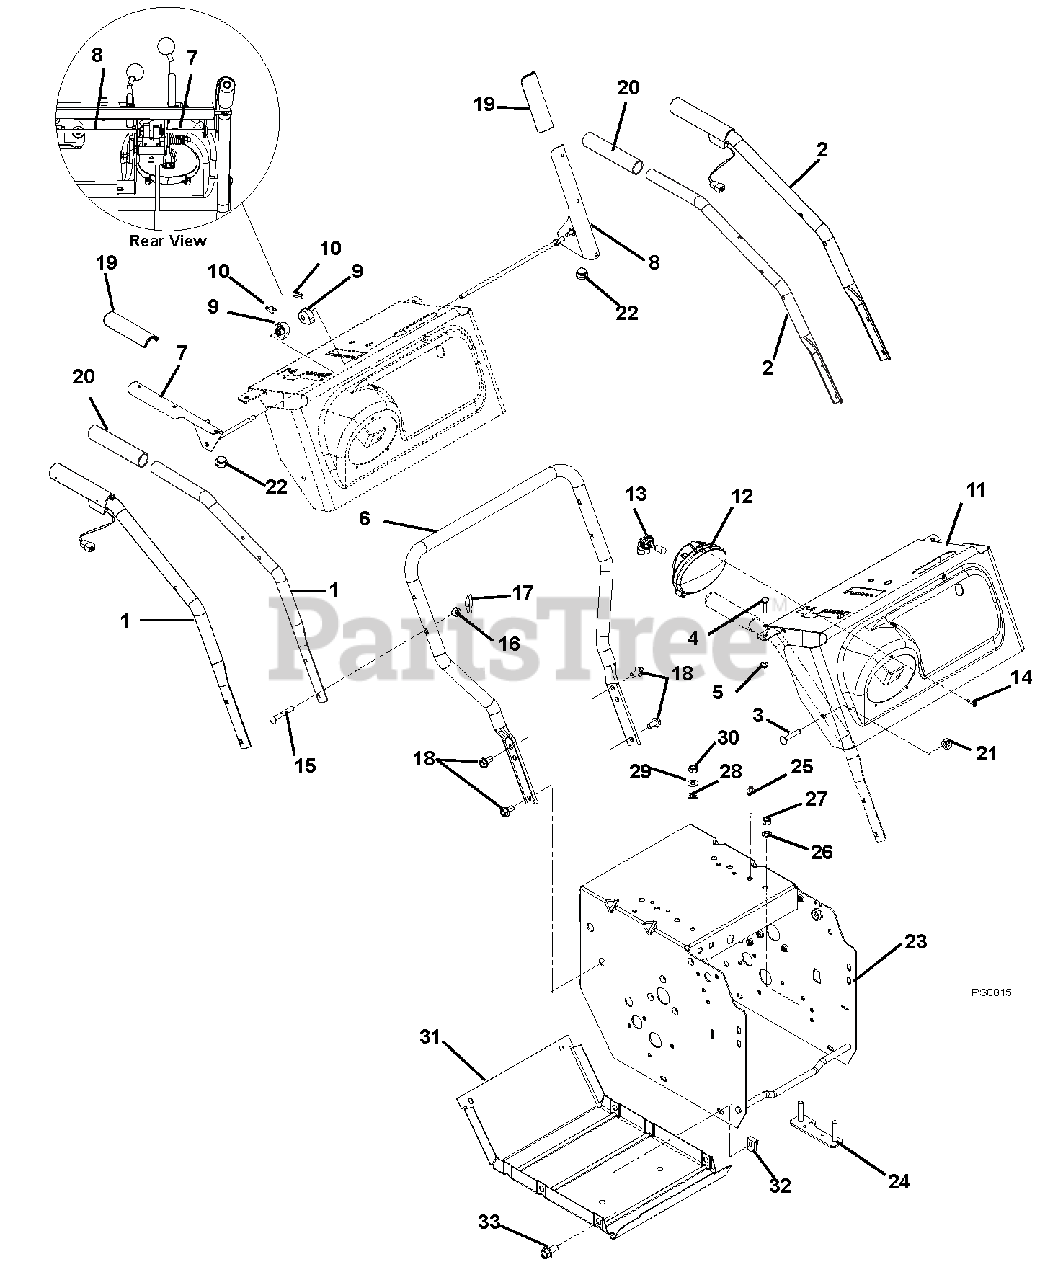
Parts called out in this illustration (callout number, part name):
1	HANDLEBAR, UPPER-RH
1	HANDLEBAR, UPPER RH-W/HW
2	HANDLEBAR, UPPER-LH
2	HANDLEBAR, UPPER LH-W/HW
3	@BLT-RDHDSQNK .31-18X1.75 G5YZ
4	BLT-RDHDXLSQNK.25-20X1.25 G5ZC
5	@NUT-LK-TOP-FLG .25-20 YWZC
6	HANDLEBAR, LOWER - DELUXE
7	LEVER, RH-ATTACHMENT
8	LEVER, LH-TRACTION
9	CAM, INTERLOCK
10	PIN, SPRING CLIP
11	DASH PANEL W/CONTROL DECAL
11	PANEL-W/CONTROL DECAL
12	LIGHT, HALOGEN ASSY.
13	BULB, LIGHT-HALOGEN 20W
14	SCR-TAP 10-16X.75 HI-LO PPH
15	@BLT-RDHDSQNK .31-18X2.25 G5YZ
16	SPACER, HANDLEBAR
17	KNOB - WING .312-18 UNC
18	BLT-SERHFWH .38-16X.75 YWZC
19	GRIP, CLUTCH LEVER, LH AND RH
20	HANDLE GRIP
21	@NUT-LK-CTR .31-18 YWZC
23	FRAME, MAIN
24	STRAP, ENGINE BOLT-WELDMENT
25	RVT-POP .187 YZ
26	WSHR-LK .312X.097 HVY YWZC
27	@NUT-HEX .31-18 YWZC
28	WSHR-LOCK INT .31 YWZC
29	@WSHR-FL-STL.344X.688X.065YWZC
30	@NUT-LK-CTR .31-18 YWZC
31	COVER, BOTTOM
32	NUT-RTNR .25-20X.56
33	BLT-HEX .25-20X.75 HWH YZ GR5
